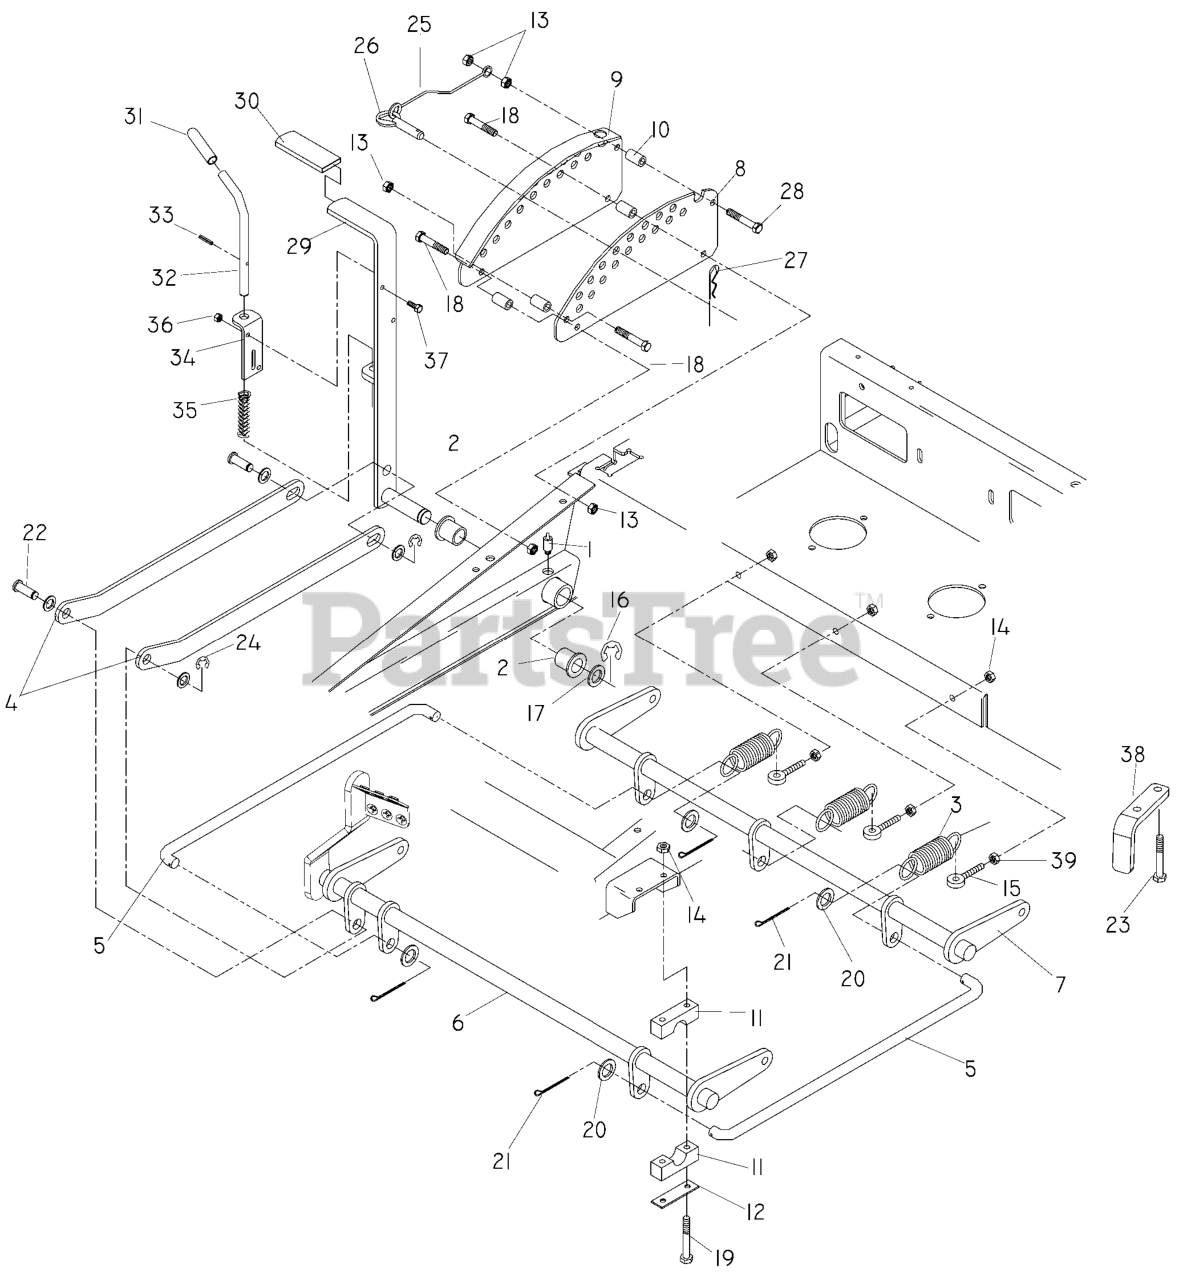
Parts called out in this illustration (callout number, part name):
1	GREASE ZERK LONG
2	BUSHING, FLANGED
3	DECK LIFT SPRING
4	LIFT LINKAGE,PAINTED
5	CONNECTING LINK
6	LIFT SHAFT ASM, FRONT
7	SHAFT LIFT REAR
8	ADJ. PLATE PAINTED
9	ADJ. PLATE WLDMNT
10	DECK LIFT SPACER
11	PILLOW BLOCK
12	REINFORCEMENT BAR
13	NUT 3/8-16 NYLOC
14	NUT 5/16 NYLOC
15	EYEBOLT, RH
16	E-RING 7/8
17	BSHG .875 X 1.375 X .074 ZD
18	HCS 3/8C X 2 1/2
19	HCS 5/16C X 2-3/4
20	WASHER 5/8 FLAT
21	COTTER PIN
22	CLEVIS PIN
23	BOLT 3/8-16 X 1.0
24	E-RING 5/8
27	HAIRPIN #4
28	SCREW 3/8C X 2 3/4 HEX CAP
29	LIFT LEVER WELDMENT
34	PIN MT, UPPER
36	NUT 1/4C CENTER LOCK
37	HCS 1/4C X 3/4 HCS
39	NUT 5/16C WHIZ
